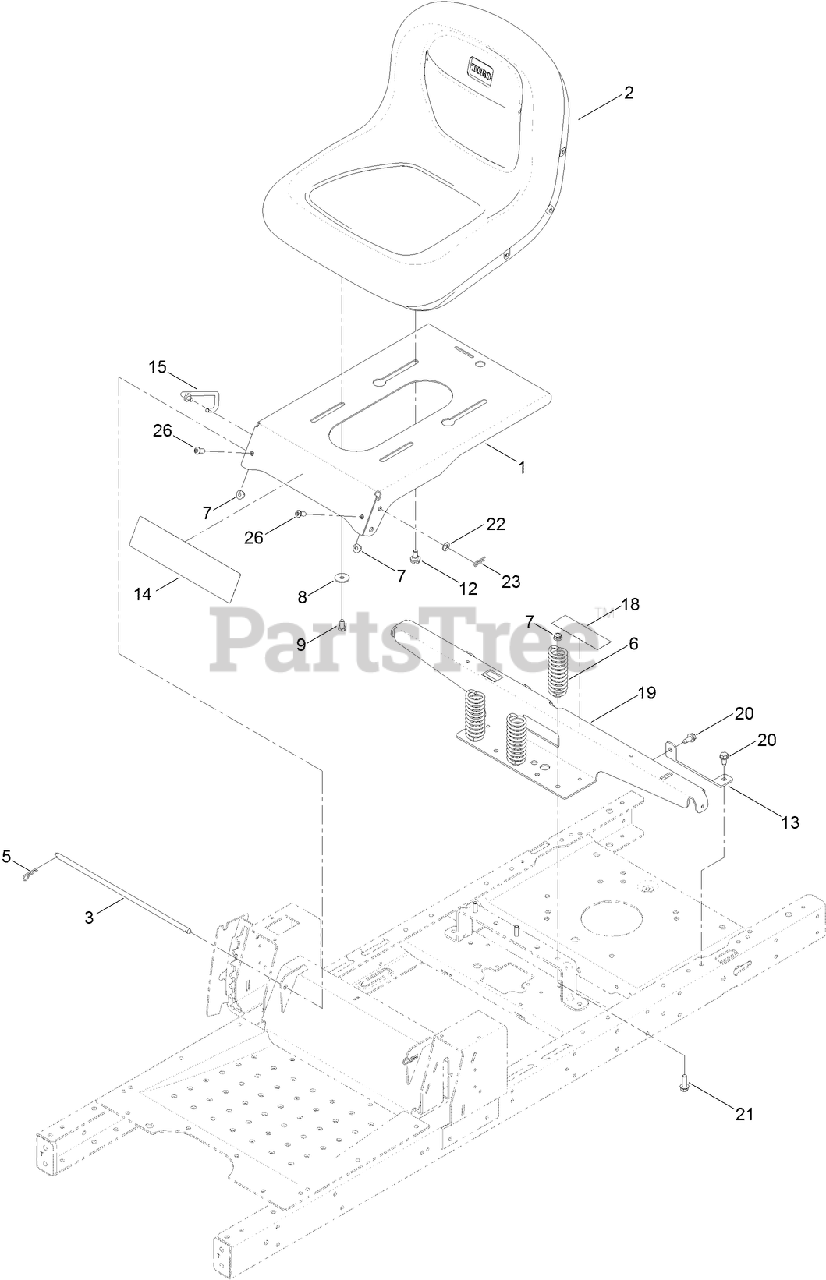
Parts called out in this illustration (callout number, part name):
1	PAN-SEAT
2	SEAT-15 INCH
3	ROD-PIVOT, NARROW
5	PIN-COTTER
6	SPRING-COMPRESSION
7	NUT-HF, NI
8	WASHER-PIVOT
9	SCREW-HH
12	BOLT-SHOULDER,HFH
13	SUPPORT-TANK, REAR
14	DECAL-TIMECUTTER
15	STOP-SEAT
18	DECAL-SERVICE, CE
19	SUPPORT-POD
20	SCREW-HWHTF
21	SCREW-HHF
22	WASHER-PLAIN
26	SCREW-HSBH
